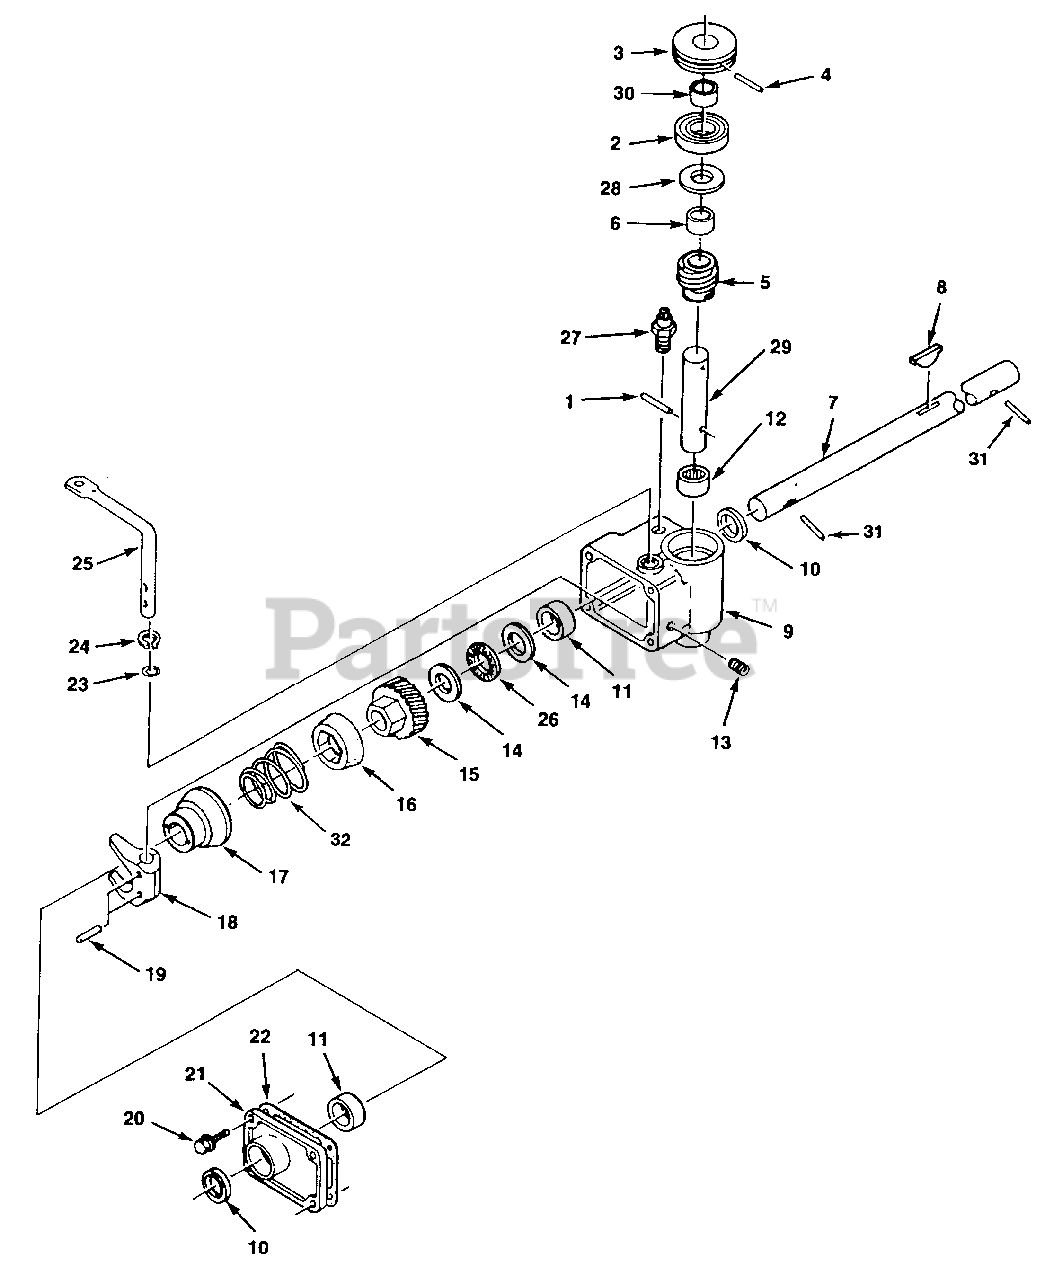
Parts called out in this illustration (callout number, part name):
1	Pin-roll 3/16 x 7/8
2	Bearing - ball
3	Pulley - drive
4	Pin-roll 3/32 x 1-1/4
5	Worm w/spacer
6	Spacer - worm
7	Shaft - drive
8	Key - Woodruff
9	Housing - gear
11	Bushing - sleeve
12	Bearing - needle
13	Plug - pipe
14	Race - thrust
15	Gear - helical
16	Cone - friction
17	Drum - clutch
18	Fork - shift
19	Pin - groove
20	Screw - hex 1/4-20 x 7/8
21	Cover - gear box
22	Gasket - cover
24	Ring - retainer
25	Lever - shift
26	Bearing - needle
28	Washer - flat
29	Shaft-worm
30	Spacer - pulley
31	Pin - roll 1/8 x 7/8
32	Spring - clutch
